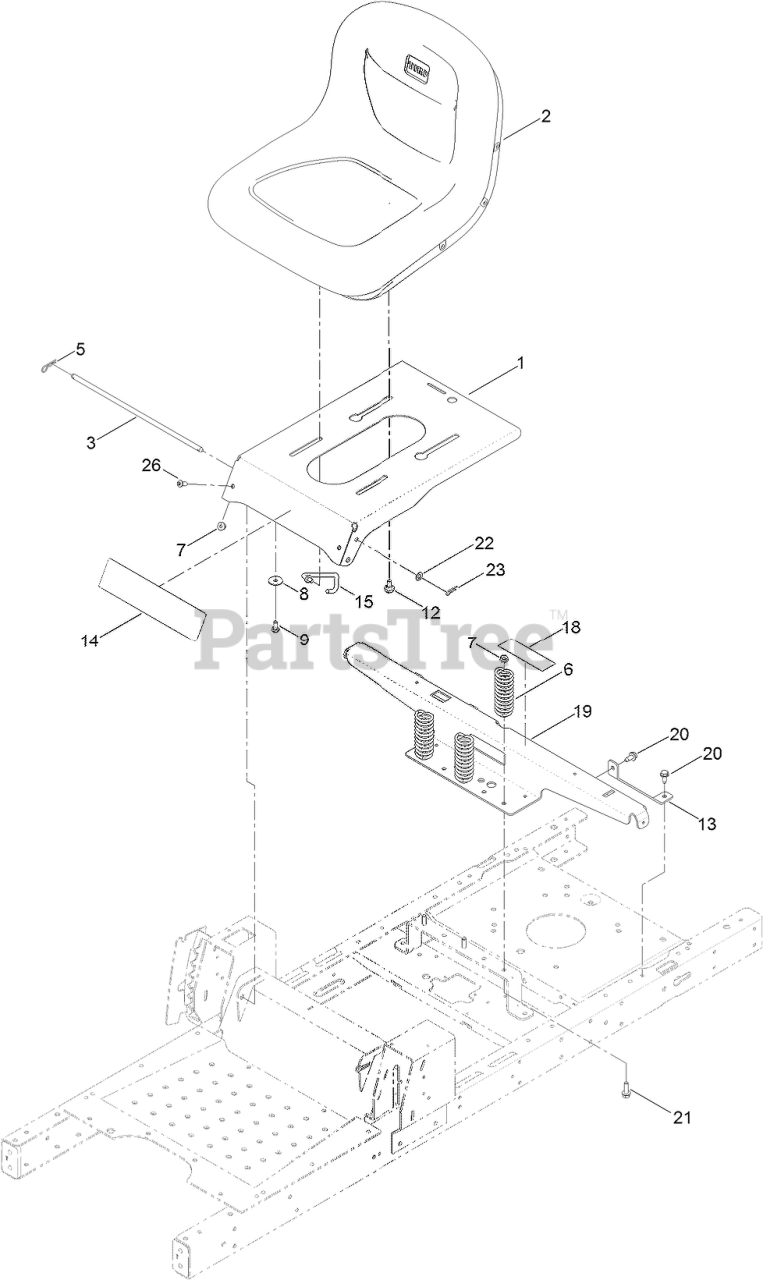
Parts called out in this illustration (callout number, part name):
1	PAN-SEAT
2	SEAT-15 INCH
3	ROD-PIVOT, NARROW
5	PIN-COTTER
6	SPRING-COMPRESSION
7	NUT-HF, NI
8	WASHER-PIVOT
9	SCREW-HH
12	BOLT-SHOULDER
13	SUPPORT-TANK, REAR
14	DECAL-TIMECUTTER
15	STOP-SEAT
18	DECAL-SERVICE, CE
19	SUPPORT-POD
20	SCREW-HWHTF
21	SCREW-HHF
22	WASHER-PLAIN
23	PIN-COTTER
26	SCREW-HSBH
